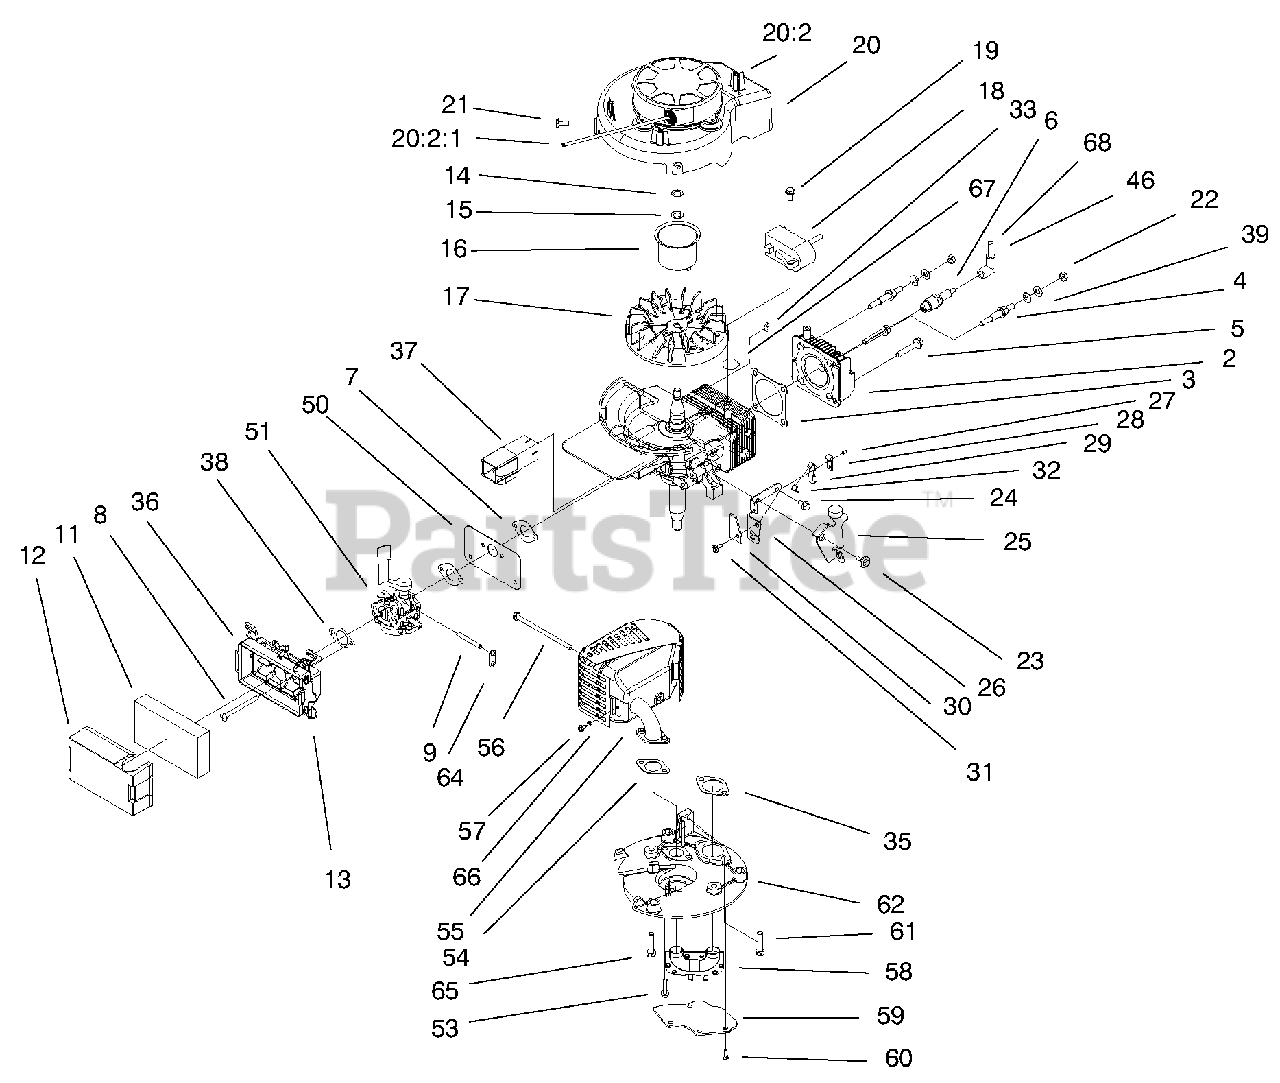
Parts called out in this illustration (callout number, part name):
1	E-S/Block Ser. S
2	Head-(Mach)
3	Gasket-Head
5	Bolt-Head
6	Plug-Spark
7	Gasket-Intake
8	Screw Xe
9	Hose-Primer
11	Filter-Air
12	Cover-Air Filter
13	Retainer-Fil. Ev
14	Nut Xev
15	Washer-Lock Xev
16	Cup-Starter
17	Flywheel Machined
18	Ignition-Cd Ev
19	Screw-Cd Mtg Xev
20	Shroud-Recoil
20:2	Recoil And Decal ASM
21	Screw-HH
23	Screw-Shoulder
24	Screw-HWH
25	Brake Plate Ay Ev
26	Plate-Brake Mtg
27	Rivet-Plastic Ev
28	Strap-Insulation
29	Strap-Ground Ev
30	Stop-Gr Strap Ev
31	Screw-Special Vex
32	Wire-Lead E
33	Key Xev
35	Gasket-Exhaust
36	Base Ay-(Air Filter)
37	Tunnel E
38	Gasket-Filter
39	Washer-Belleville
46	Cover & Term. Ay S
50	Shield-Carb. E
51	Carburetor ASM With Gaskets
53	Screw-Hex Washer Hd
55	Muffler & Guard ASM
56	Bolt-Console E
57	Screw-Hex Washer Hd
58	Pipe-Transfer
59	Cover-Muffler
60	Screw-HH
61	Screw-HH
62	Plate-Muffler
64	Hose-Retainer
65	Screw-HH
66	Washer-Lock
67	Strap-Tie Xef
68	Ht Lead&cover Xev
